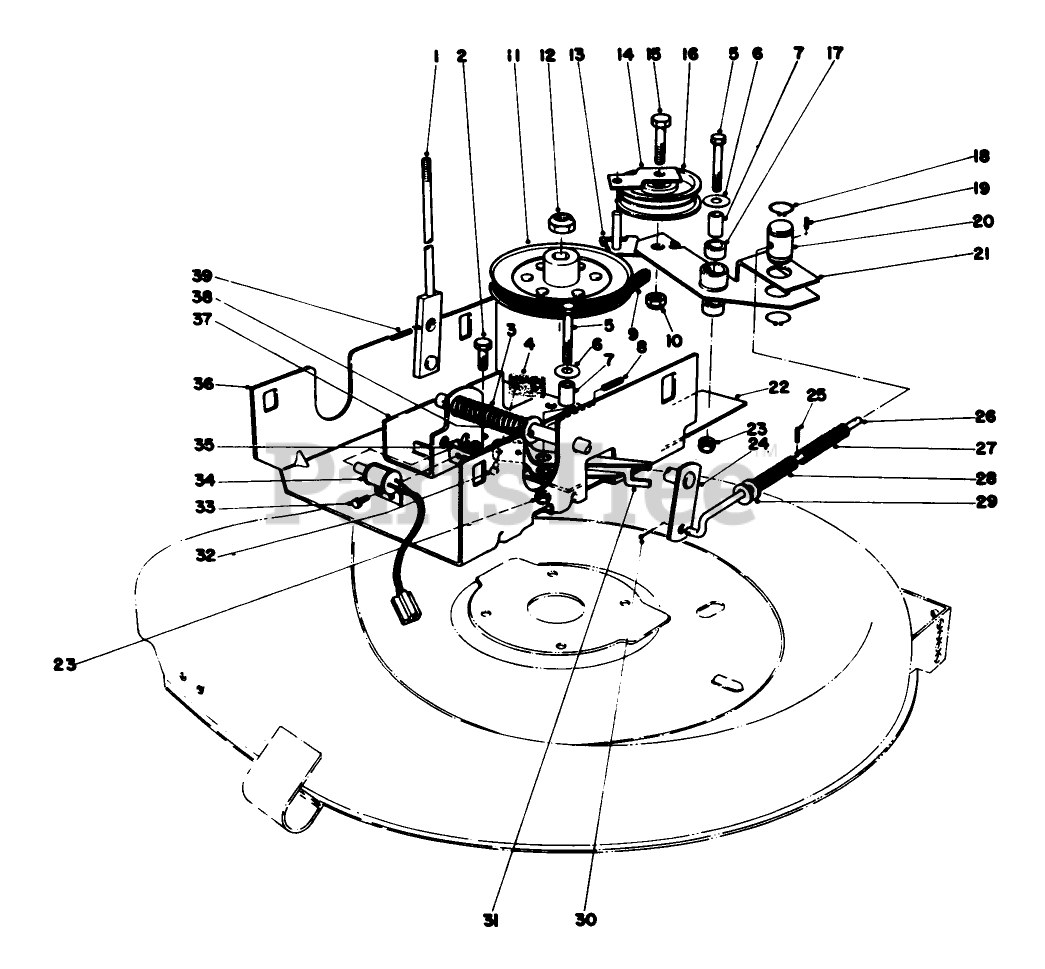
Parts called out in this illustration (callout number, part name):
2	SCREW-HH
5	SCREW-HH
6	WASHER-PLAIN
7	PIVOT SPACER
8	PIN-SPRING
9	V-BELT
10	NUT-LOCK, SIDE
12	NUT-SPECIAL
15	SCREW-HH
17	Bushing
18	RING-RETAINING
19	PIN-ROLL
23	NUT-LOCK, CONE
25	PIN-SPRING
30	PIN-COTTER
35	NUT-KEPS
36	CHANNEL HT ADJ *R
38	WASHER-FLAT
39	PIN-SPIRAL
